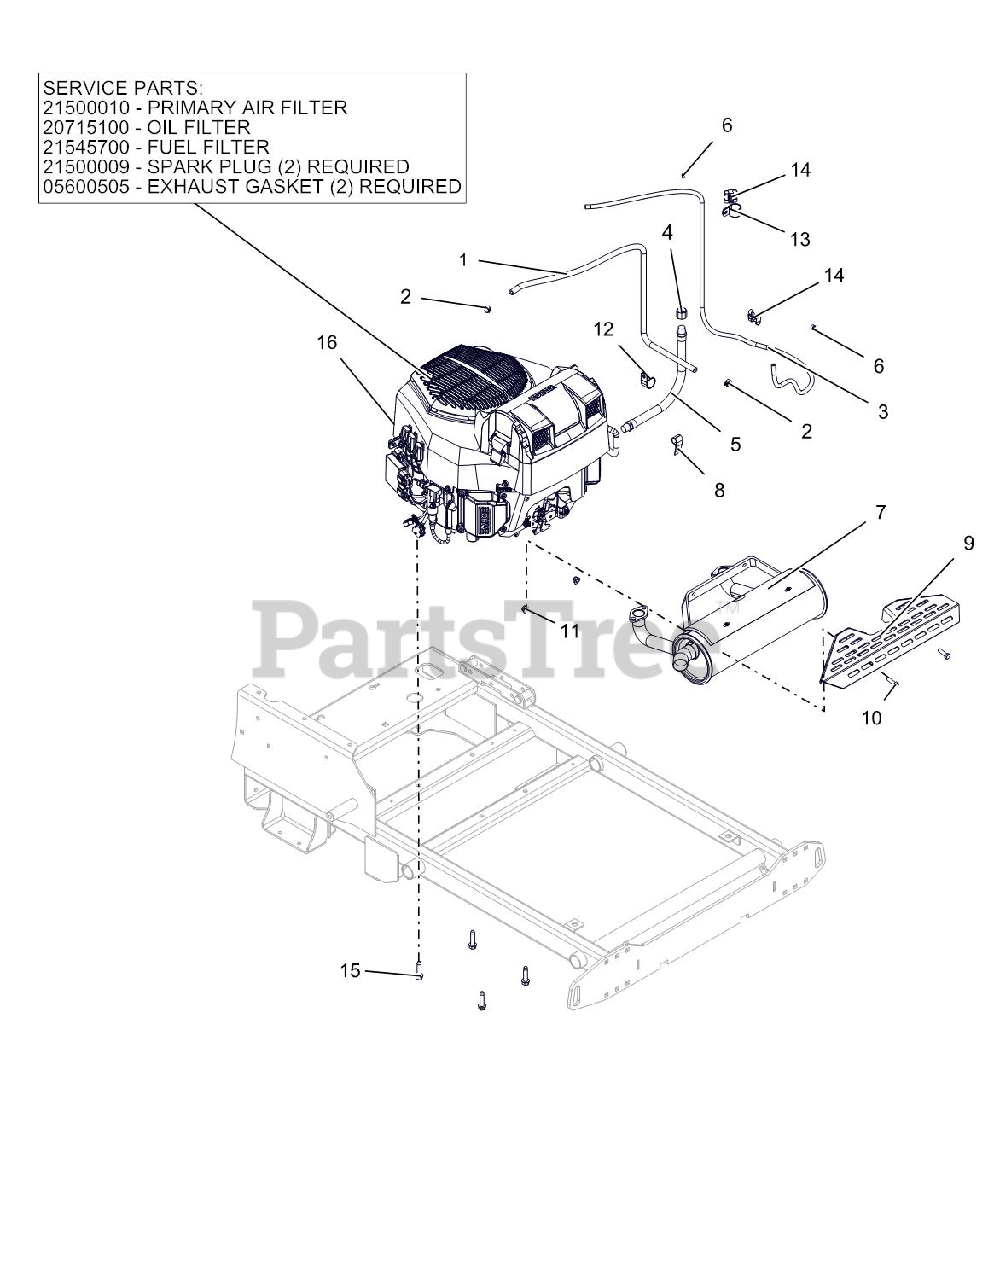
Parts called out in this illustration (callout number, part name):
1	HOSE, .25 LOW-PERM BULK GAS
2	CLAMP, FUEL LINE
3	HOSE, .188 LOW-PERM BULK GAS
4	PIPE CAP 3/8 NPT FEMALE
5	HOSE,HYD .38-14-0K M6N0-M6N0
6	CLAMP-HOSE, SPRING .188
7	MUFFLER, PS KOHLER EFI
9	GUARD, MUFFLER
10	BLT-HEX .31-18X1.00 GR5 YWZC
11	NUT-LK-NYL-FLG .31-18 YWZC
12	CLAMP, COUSHIONED STEEL REV
13	CLAMP, COUSHIONED STEEL REV
14	CLIP, T, .38-.50
15	SCR-TAP .38-16X1.50 HWH TR YZ
16	GASKET, MUFFLER COURAGE TWIN
16	AIR CLEANER, KOHLER CONFIDANT
16	FILTER-FUEL KOHLER COURAGE PRO
16	PLUG, SPARK KOHLER
16	OIL FILTER KOHLER
16	ENGINE, KOHLER EZT740
